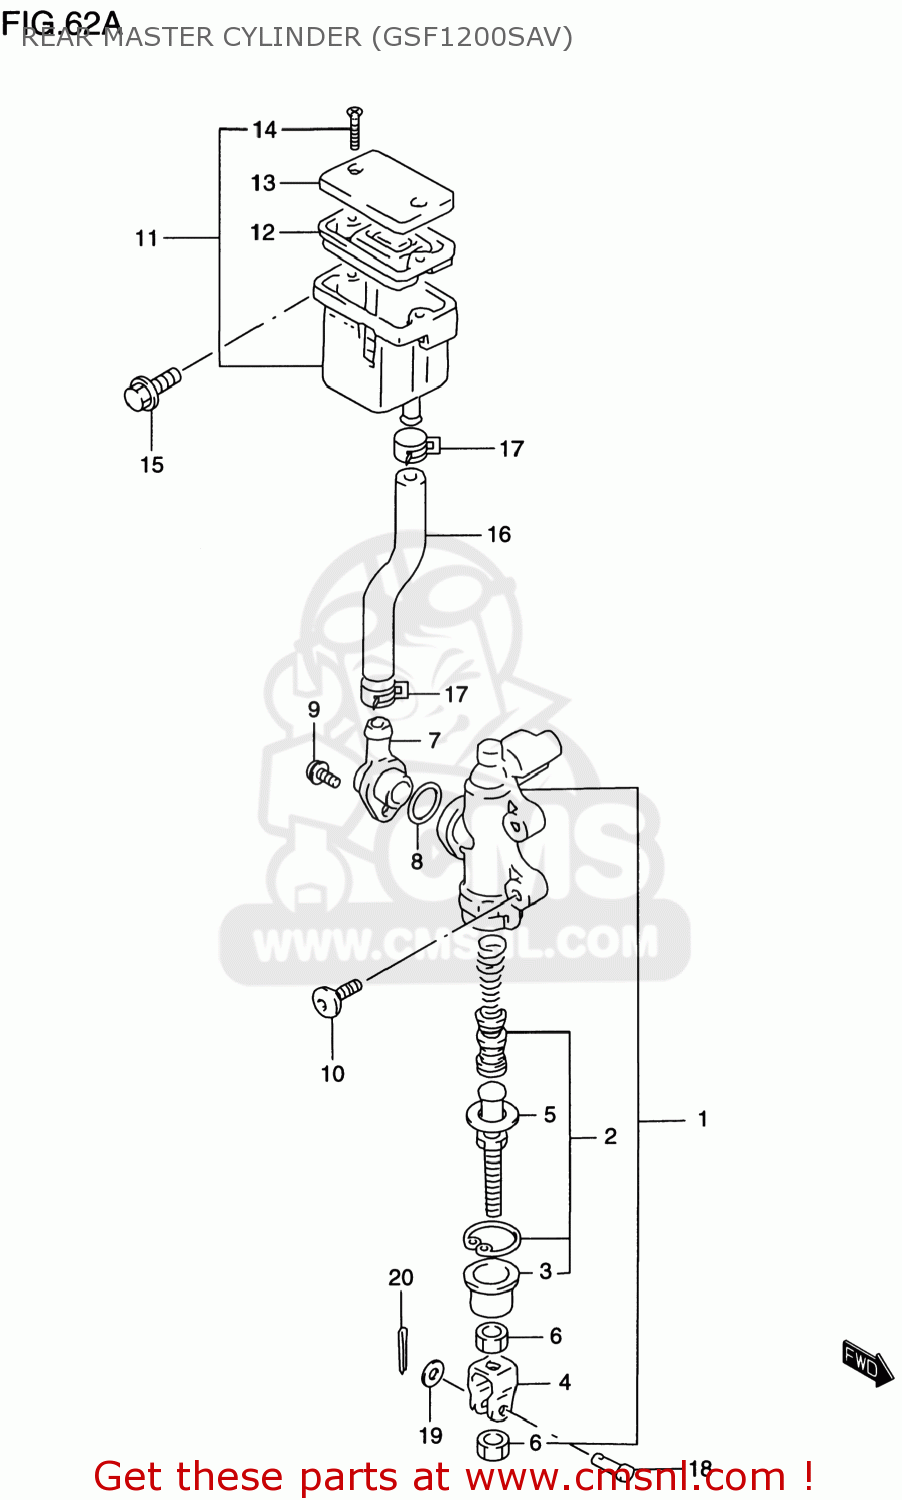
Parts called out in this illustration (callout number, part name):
1	CYLINDER ASSY,RR MASTER
2	PISTON/CUP SET
3	BOOT
4	YOKE
5	ROD,PUSH
6	NUT
7	CONNECTOR
8	O RING
9	SCREW
10	BOLT 8X20
11	TANK ASSY,RESERVOIR
12	DIAPHRAGM
13	CAP
14	SCREW
15	BOLT
16	HOSE,RESERVOIR TANK
17	CLIP
18	PIN
19	WASHER
20	PIN
